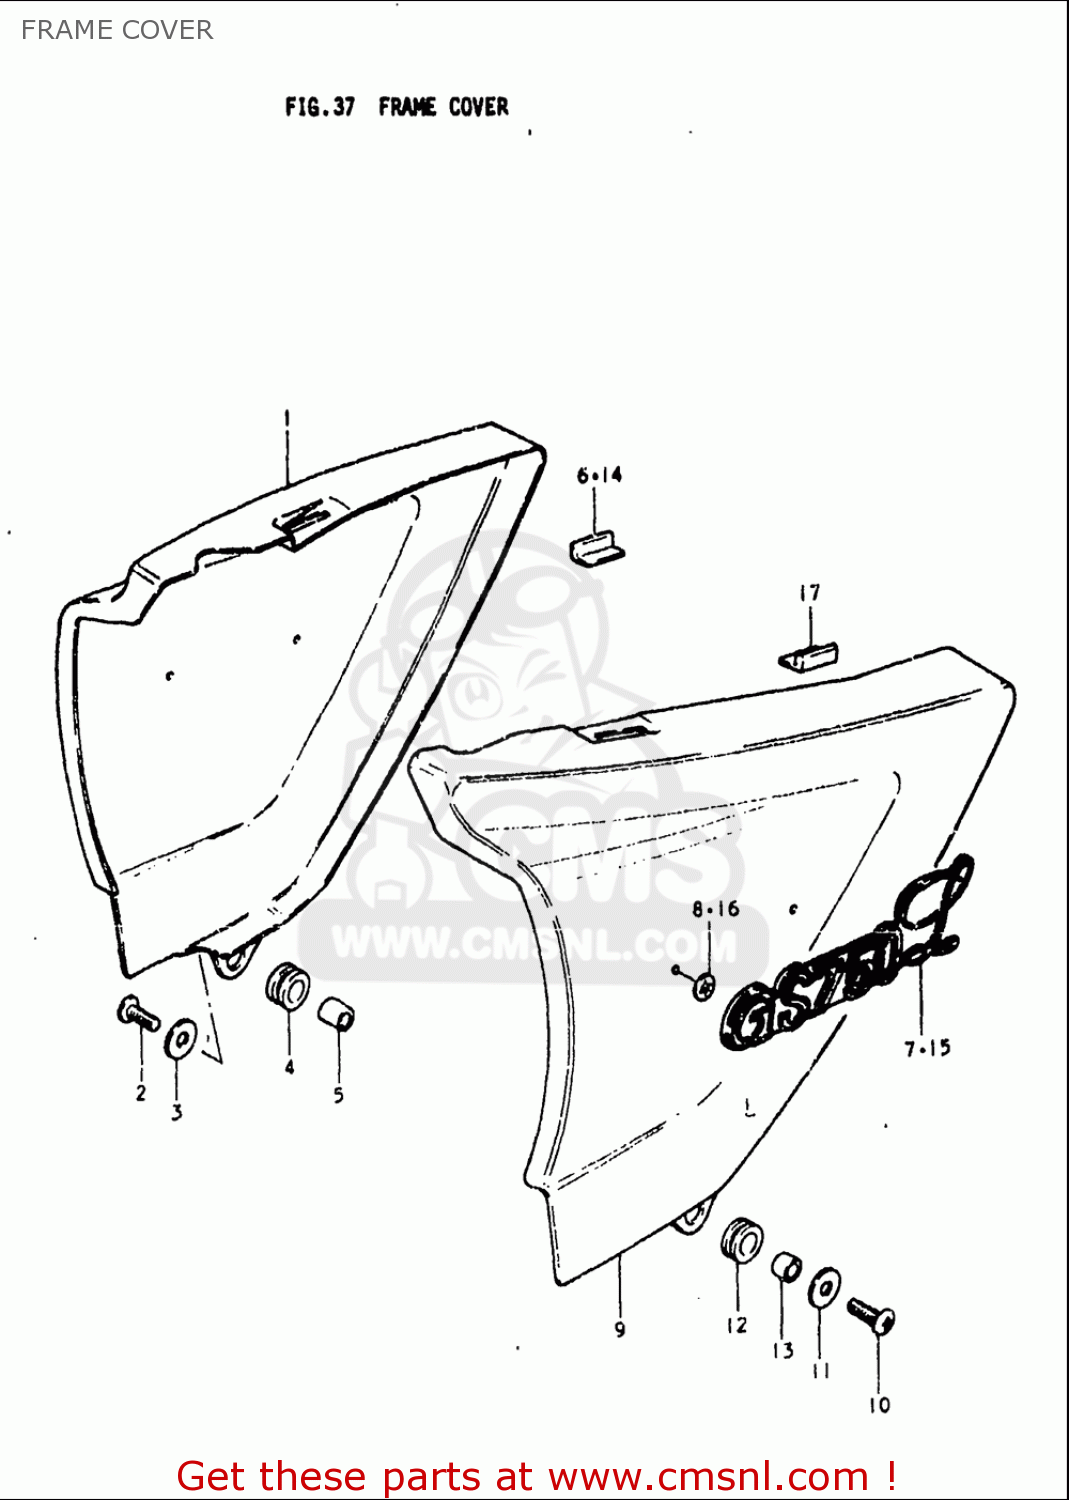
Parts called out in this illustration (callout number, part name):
1	COVER,FRAME,RIGHT
2	SCREW
3	WASHER(6.5X18X1.6)
4	CUSHION
5	SPACER(6.5X10X10)
6	CUSHION,FRAME COVER
7	EMBLEM,FRAME COVER
8	NUT
9	COVER,FRAME,LEFT
10	SCREW
11	WASHER(6.5X18X1.6)
12	CUSHION
13	SPACER(6.5X10X10)
14	CUSHION,FRAME COVER
15	EMBLEM,FRAME COVER
16	NUT
17	CUSHION,FRAME COVER
